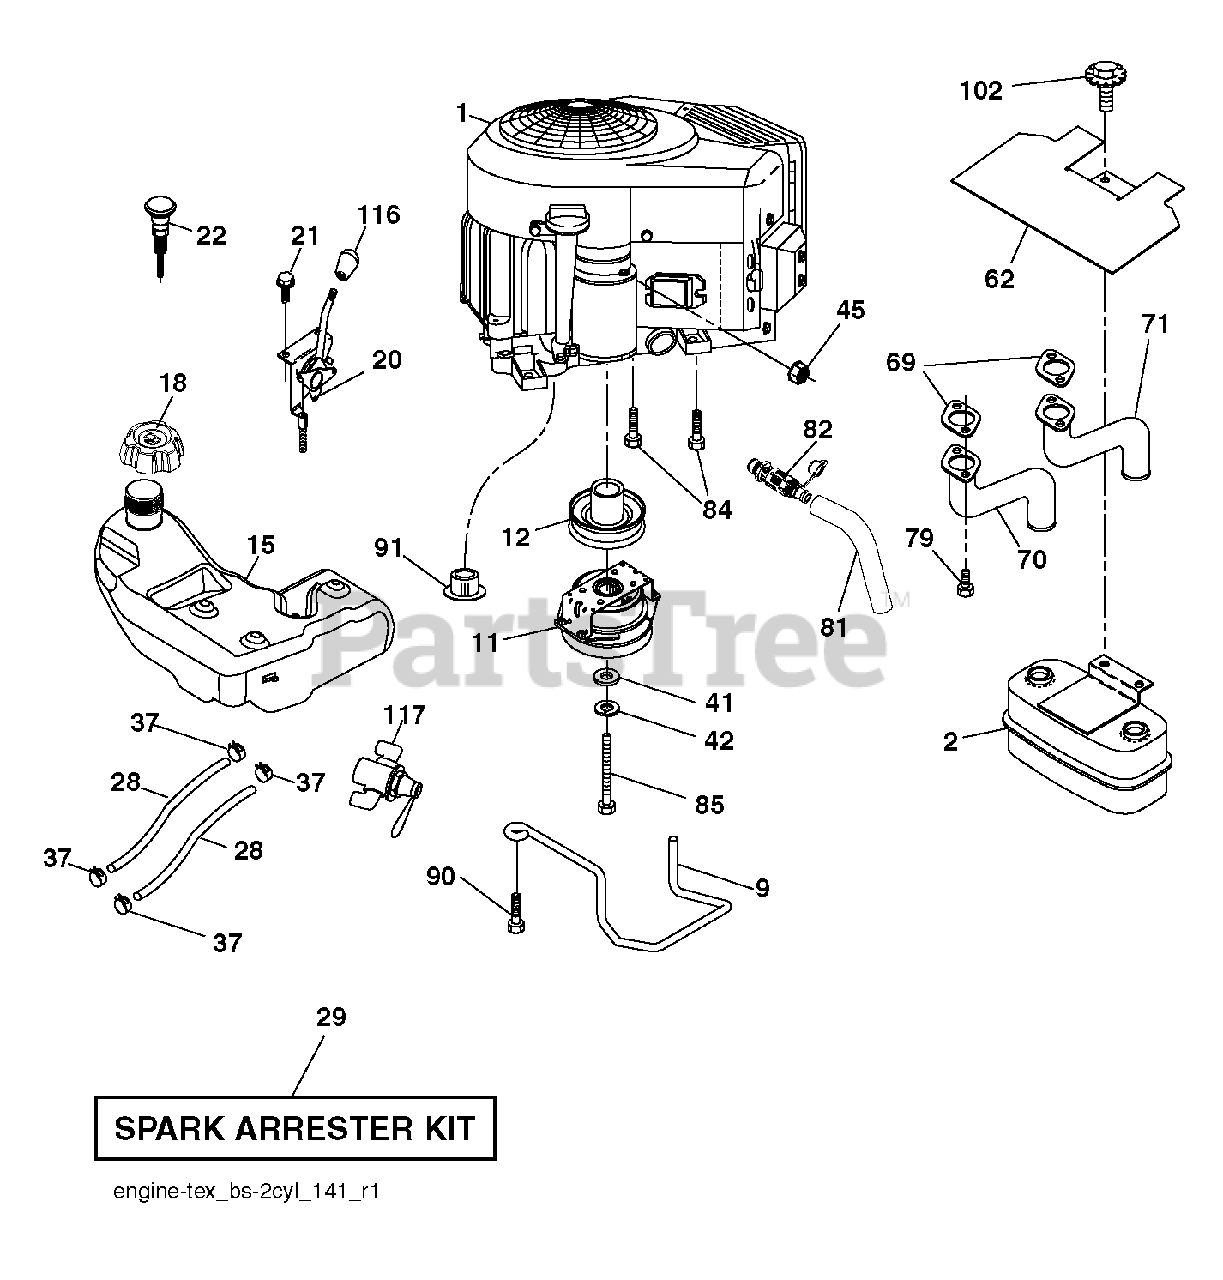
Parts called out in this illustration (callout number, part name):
2	MUFFLER.ASM.TWN.EXTNDED.DFLCTR
9	KEEPER BELT ENGINE
11	CLUTCH.OGURA.5.0PD.GT1.5A-EH07
12	PULLEY.ENGINE.TUFFTORQ
18	CAP.ASSY.FUEL.3".N-EPA.GRY.498
20	CONTROL.THROTTLE.PRO.
21	SCREW.#10 X 0.750.BOS
22	CONTROL, CHOKE
28	HOSE.1/4".FUEL.LINE.61".LENGTH
29	KIT.SPARK ARRESTOR 794945 B&S
37	HOSE CLAMP
42	LOCKWASHER
45	NUT
62	SHIELD.HEAT.MUFFLER
69	GASKET.MUFF 806237 NOW 806425
70	EXHAUST.TUBE.MUFFLR.LH.VANG
71	EXHAUST.TUBE.MUFFLR.RH.VANG
79	Muffler Tube Screw, Vanguard
81	TUBE, DRAIN OIL ASM.
82	VALUE.OIL.DRAIN
84	SCREW.3/8-16
85	BOLT HEX 7/16-20 X 3.75 GR. 5
90	SCREW 3/8-16X1
91	BUSHING.1.375OD
102	SCREW
116	KNOB - SHIFT
117	VALVE FUEL RESERVE
